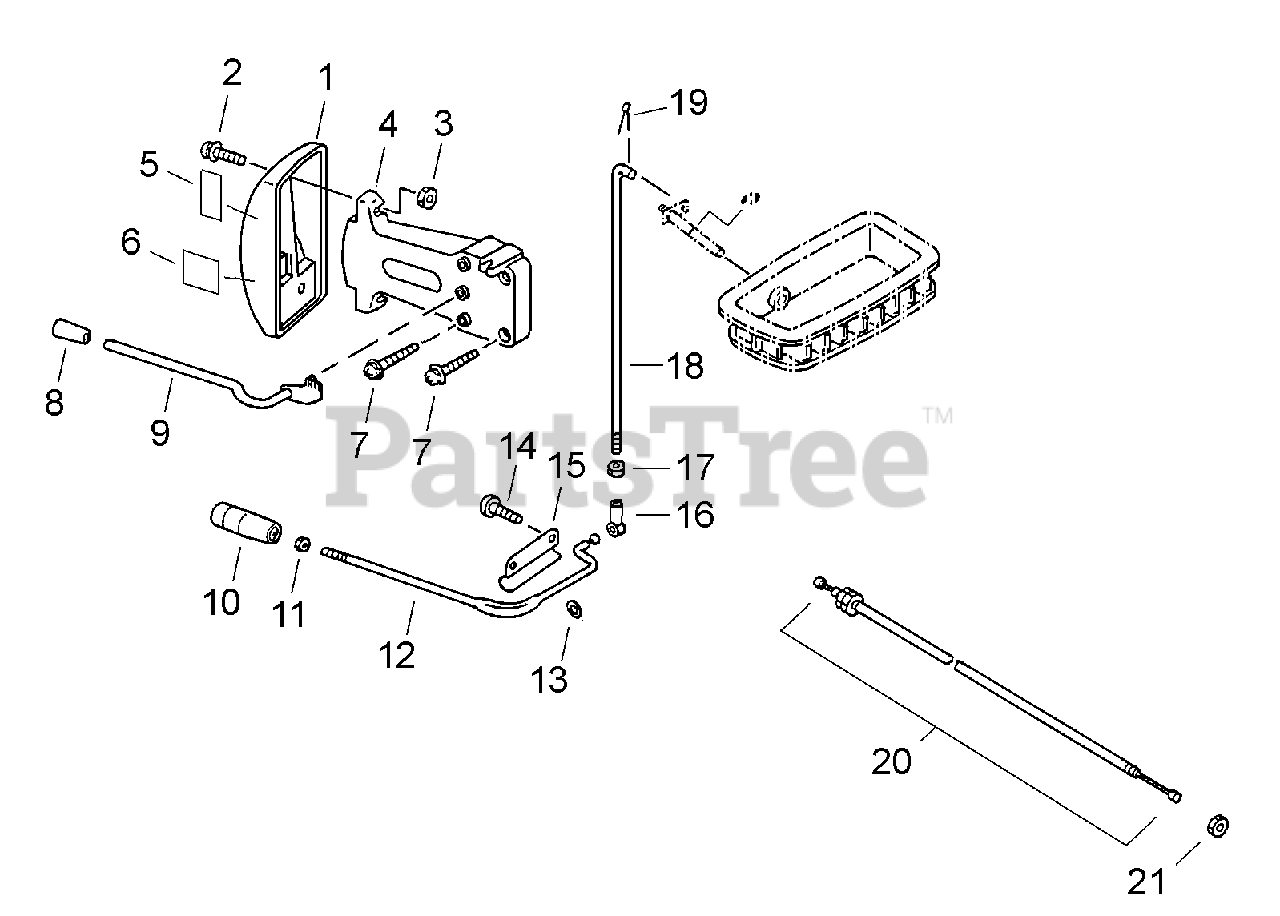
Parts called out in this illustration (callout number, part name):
1	DIAL, METERING
2	SCREW 5×25 SUS
4	BRACKET, DIAL
5	LABEL, THROTTLE
6	LABEL, STOP
7	SCREW 5×25 SUS
8	KNOB, THROTTLE CONTROL
9	LEVER, THROTTLE CONTROL
10	KNOB, SHUTTER CONTROL
12	LEVER, SHUTTER CONTROL
13	WASHER 8.5×16×1.2
14	SCREW 5×14 SUS
15	BRACKET, CONTROL LEVER
16	CONNECTOR, ROD
17	NUT M5
18	ROD, CONTROL LEVER
19	PIN, COTTER 1.8×18
20	CABLE, THROTTLE
21	NUT 6 MM
